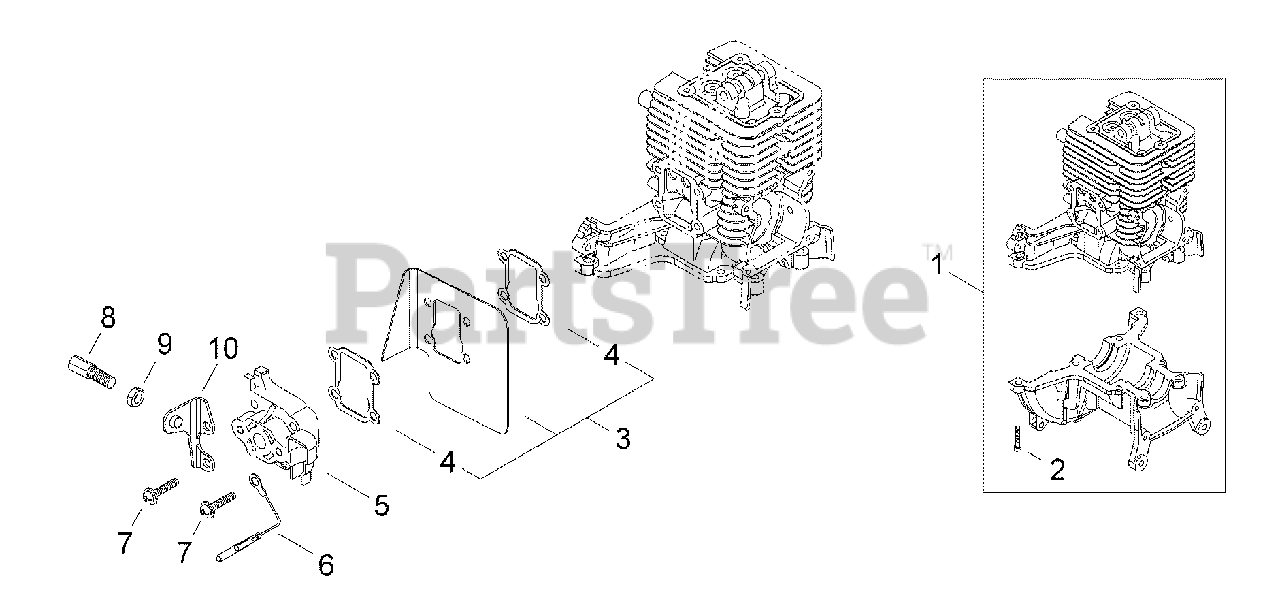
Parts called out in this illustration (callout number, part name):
1	CYLINDER BLOCK SET
2	SCREW - 5X16
3	INTAKE SHIELD ASSY
4	SHIELD, INTAKE
5	VALVE, REED
6	LEAD - GROUND
7	SCREW - 5X25
8	NUT, CABLE ADJUST
9	LOCKNUT - 6
10	BRACKET, THROTTLE CABLE
